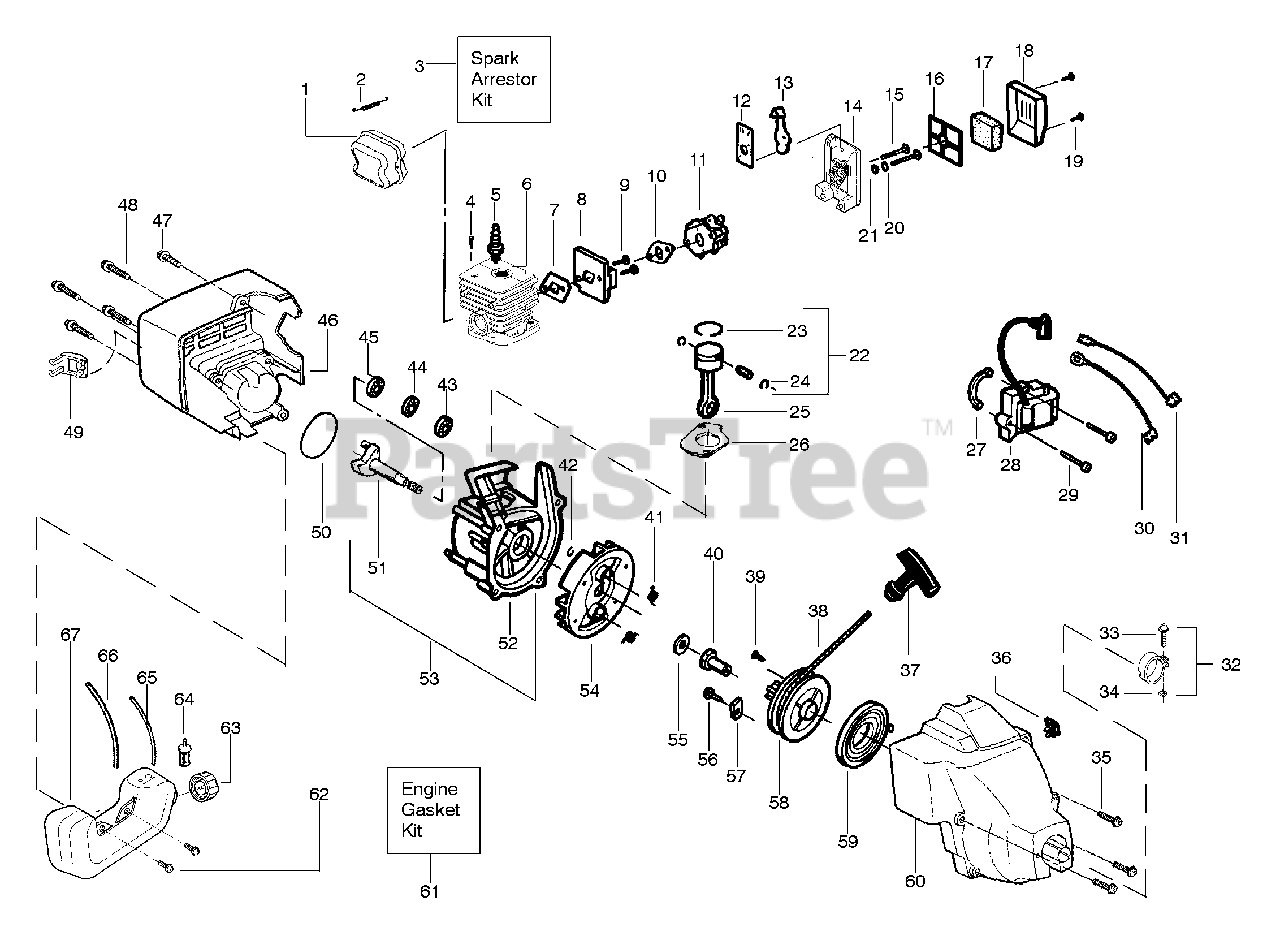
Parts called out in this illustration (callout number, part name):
1	Kit - Muffler S.A.
2	Muffler Spring
3	Kit-Spark Arrestor
4	Screw-Cylinder
5	Spark Plug (RCJ 6Y)
6	Kit - Cylinder
7	Gasket-Cyl./Carb.(kit)
8	Carb. Adaptor
10	Gasket-Carb.(kit)
11	Kit - Carburetor Ass'y
12	Choke Plate Mounting
13	Choke Shutter
16	Plate - Filter Support
17	Air Filter Foam
18	Air Filter Cover
20	Spacer-Choke
22	Kit - Piston
23	Piston Ring
24	Piston Pin Retainer
25	Connecting Rod Ass'y.
26	Gasket-Cylinder(kit)
27	Spacer-Module
28	Ignition Module
30	Assy-Ground Wire
31	Assy-Leadwire
32	Nose Cone Clamp Ass'y.
33	Screw-Nose Cone
34	Nut-Nose Cone
35	Screw
36	Kit-On/Off Switch
37	Starter Handle
38	Kit - Rope
40	Drive Coupling
41	Starter Dog Spring
42	Retain. Ring-C'shaft
43	Outer Bearing
44	Kit-C'case Seal
45	Inner Bearing
46	Assy.-Fan Hsg/Shroud
48	Screw
49	Guard-Muffler
50	O-Ring-C'case(kit)
51	Assy-Crankshaft
52	Kit-Crankcase Ass'y.
53	C'case & C'shaft Assy.
54	Flywheel Ass'y.
55	Washer-Flat
57	Retainer-Can
58	Starter Pulley Kit
59	Starter Spring
60	Kit-Fan Hsg/Shroud
61	Kit-Engine Gasket
62	Retainer
63	Assy-Fuel Cap
64	Assy-Fuel Pickup
65	Kit-Fuel Line (Small)
66	Kit-Fuel Line (Large)
67	Assy-Fuel Tank
